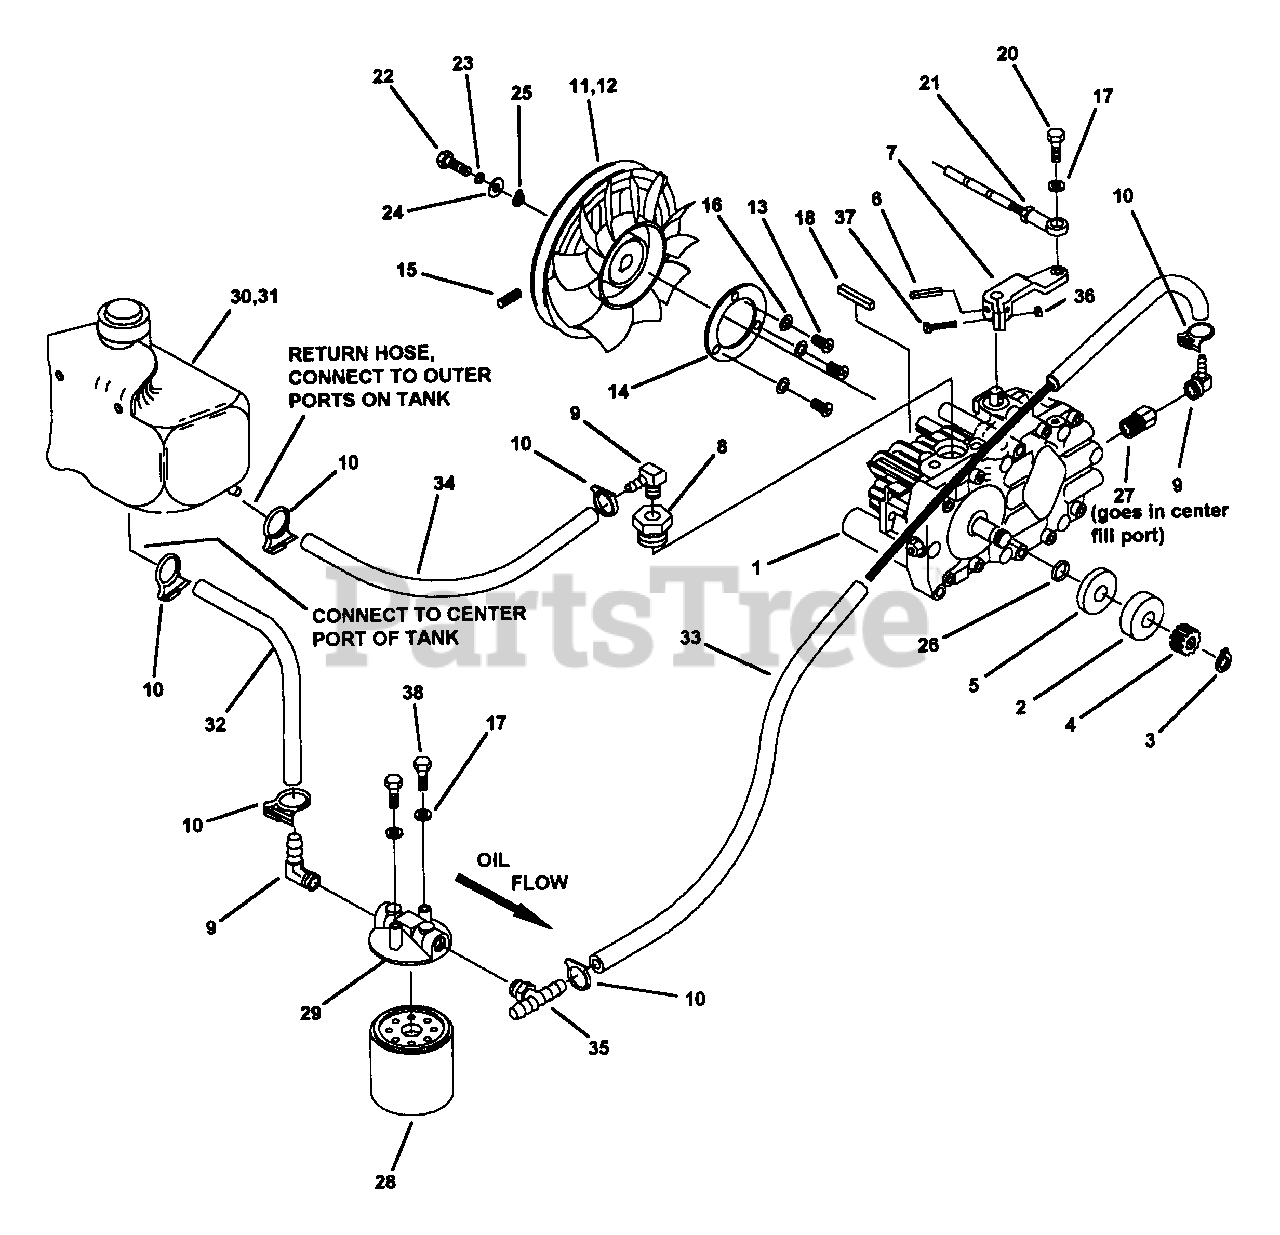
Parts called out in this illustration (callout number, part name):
1	HYDROSTAT TRANSMISSION, BDU-10L-218, LH
2	BEARING, BALL, 15MM ID
3	SNAP RING, EXT., .5 DIA
4	GEAR, 11 TOOTH
5	SPACER, BEARING
6	ROLL PIN, 5MM X 26MM
7	SHIFT ARM
8	ADAPTER, 7/8-14M TO 1/4-18F
9	HOSE BARB, 90D ELBOW, 1/4NPTM X 3/8"
10	HOSE CLAMP, 19/32-21/32, NYLON
12	FAN, 7" PLASTIC; 10 BLADE CCW
13	BOLT, 1/4-20 X 1/2", GR.5
14	WASHER, 3" O.D.
15	SETSCREW, SKHD 1/4-20 X 3/4" W/NYLOC
16	LOCKWASHER, 1/4" SPLIT SPRING
17	LOCKWASHER, 1/4" SPLIT SPRING
19	BALL JOINT, FEMALE 1/4-28
20	BOLT, 1/4-20 X 3/4" GR. 5
21	NUT, 1/4-28 (COMES WITH PUSH-PULL CABLE)
22	BOLT, 6MM X 18MM
23	LOCKWASHER, 6MM
26	O-RING SEAL
28	OIL FILTER
29	BASE, FILTER
30	TANK, 1.5 QT, CHARGE PUMP STYLE (comes with cap, item 31)
31	CAP, Oil Tank
33	HOSE, 46", L.H.
34	HOSE, 18"
36	NUT, 1/4-20, NYLOC
37	BOLT, 1/4-20 X 1", GR.5
38	BOLT, 1/4-20 X 5/8", GR.5
